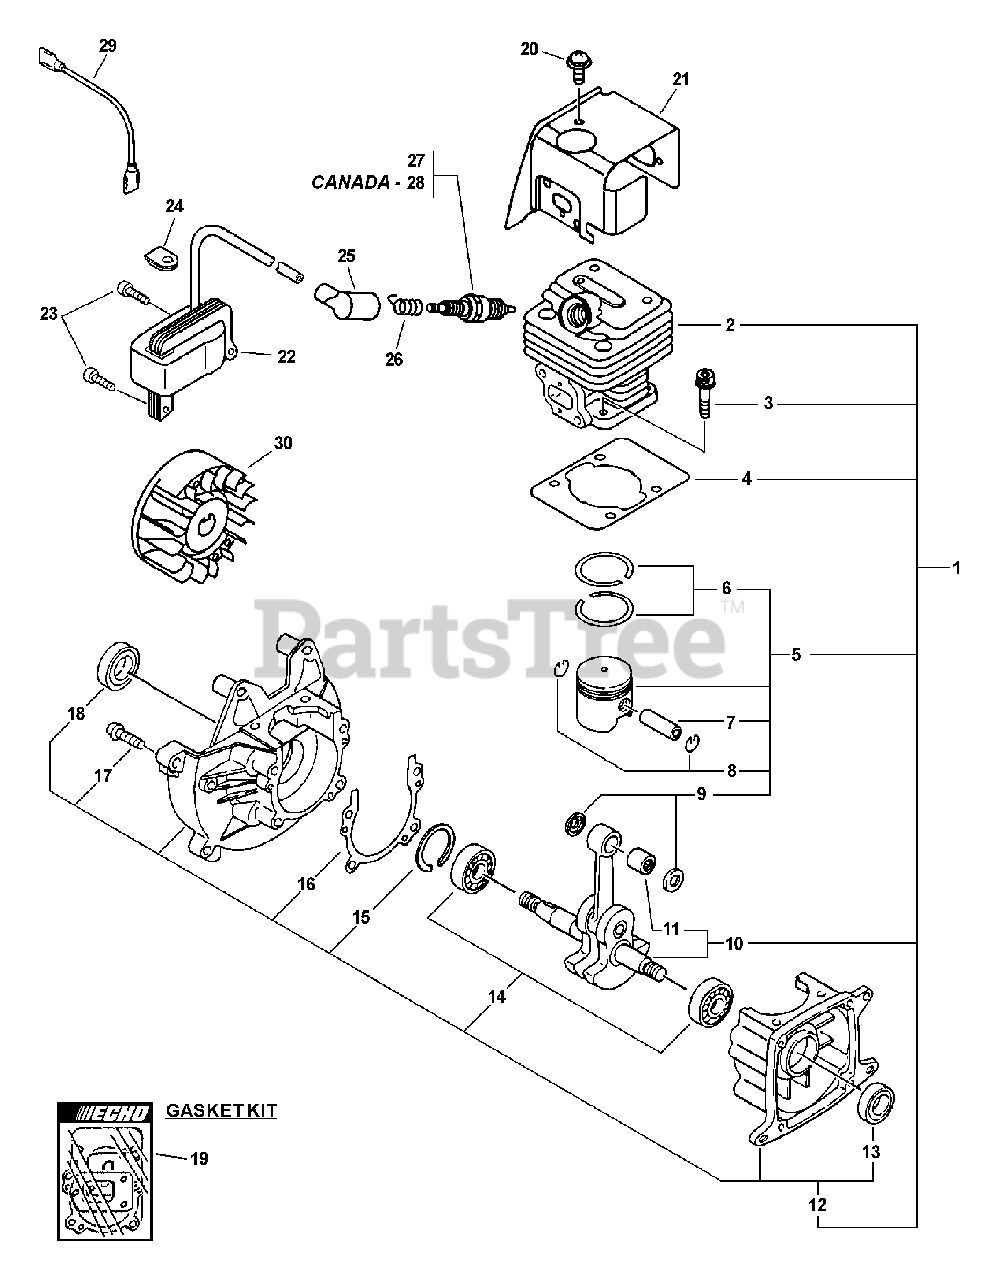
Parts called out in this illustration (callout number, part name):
1	SHORT BLOCK
2	CYLINDER
3	BOLT 5×22
4	GASKET, CYLINDER
5	PISTON KIT
6	RING, PISTON
7	PIN, PISTON 8
8	RING, SNAP
9	WASHER, THRUST
10	CRANKSHAFT ASSY
11	BEARING, NEEDLE 8
12	CRANKCASE KIT
13	SEAL, OIL 12
14	BEARING, BALL 6001
15	RING, SNAP 28
16	GASKET, CRANKCASE
17	BOLT 5×25
18	SEAL, OIL 12
19	GASKET KIT
20	SCREW 5×10
21	COVER, CYLINDER
22	COIL, IGNITION
23	BOLT 5×16
25	CAP, SPARK PLUG
26	TERMINAL, SPARK PLUG
27	SPARK PLUG - BPM-7Y
28	SPARK PLUG - BPMR7A
29	LEAD - IGNITION
30	FLYWHEEL
